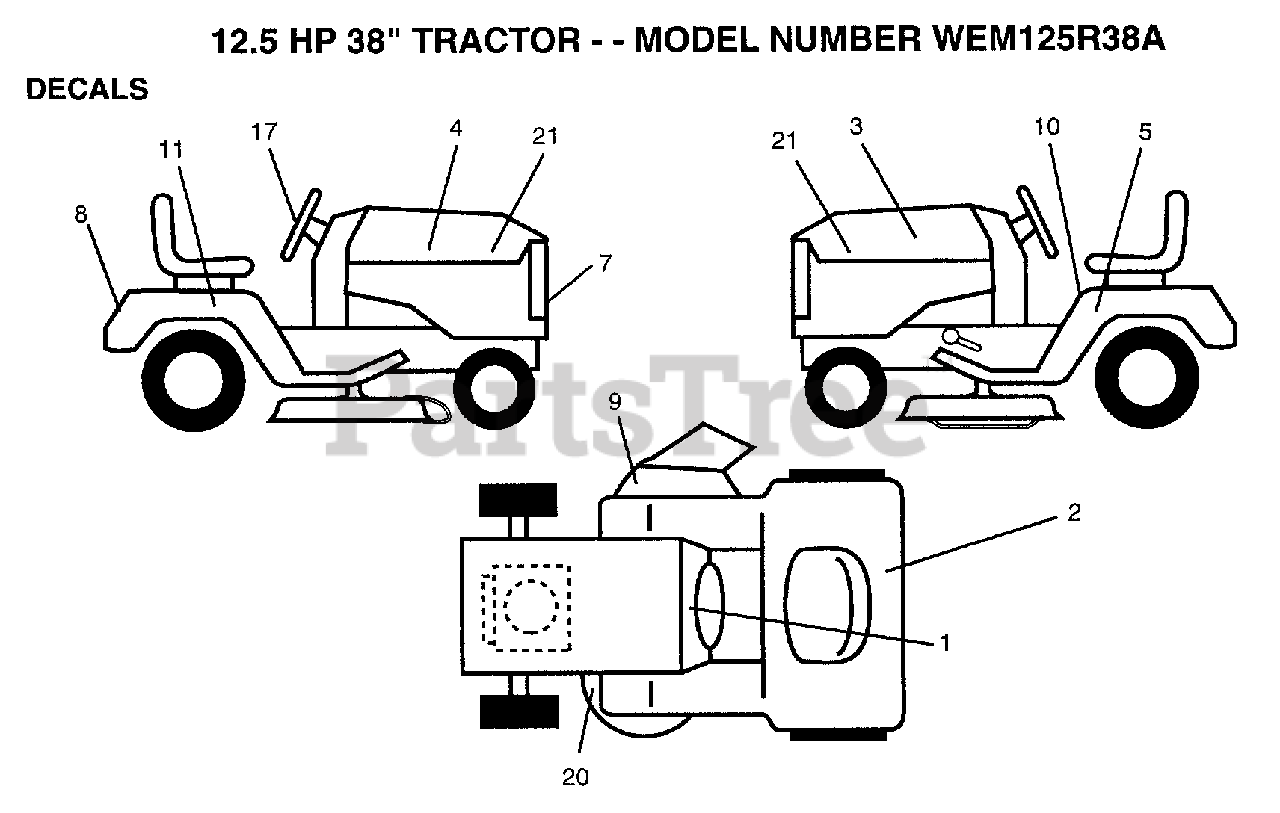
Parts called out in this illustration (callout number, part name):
1	DECAL.INST.OPER.
2	DECAL
3	DECAL STRIP HD LH
5	IND HGT DECK DECA
7	"DECAL,LIGHT BOX"
8	DECAL.FENDER
9	"DECAL, WARNING"
10	DECAL CAUTION
11	DECAL.FEND.QUICKS
17	DECAL.WHL.STRG.
20	DECAL
21	DECAL.PNL.SD.12.5
